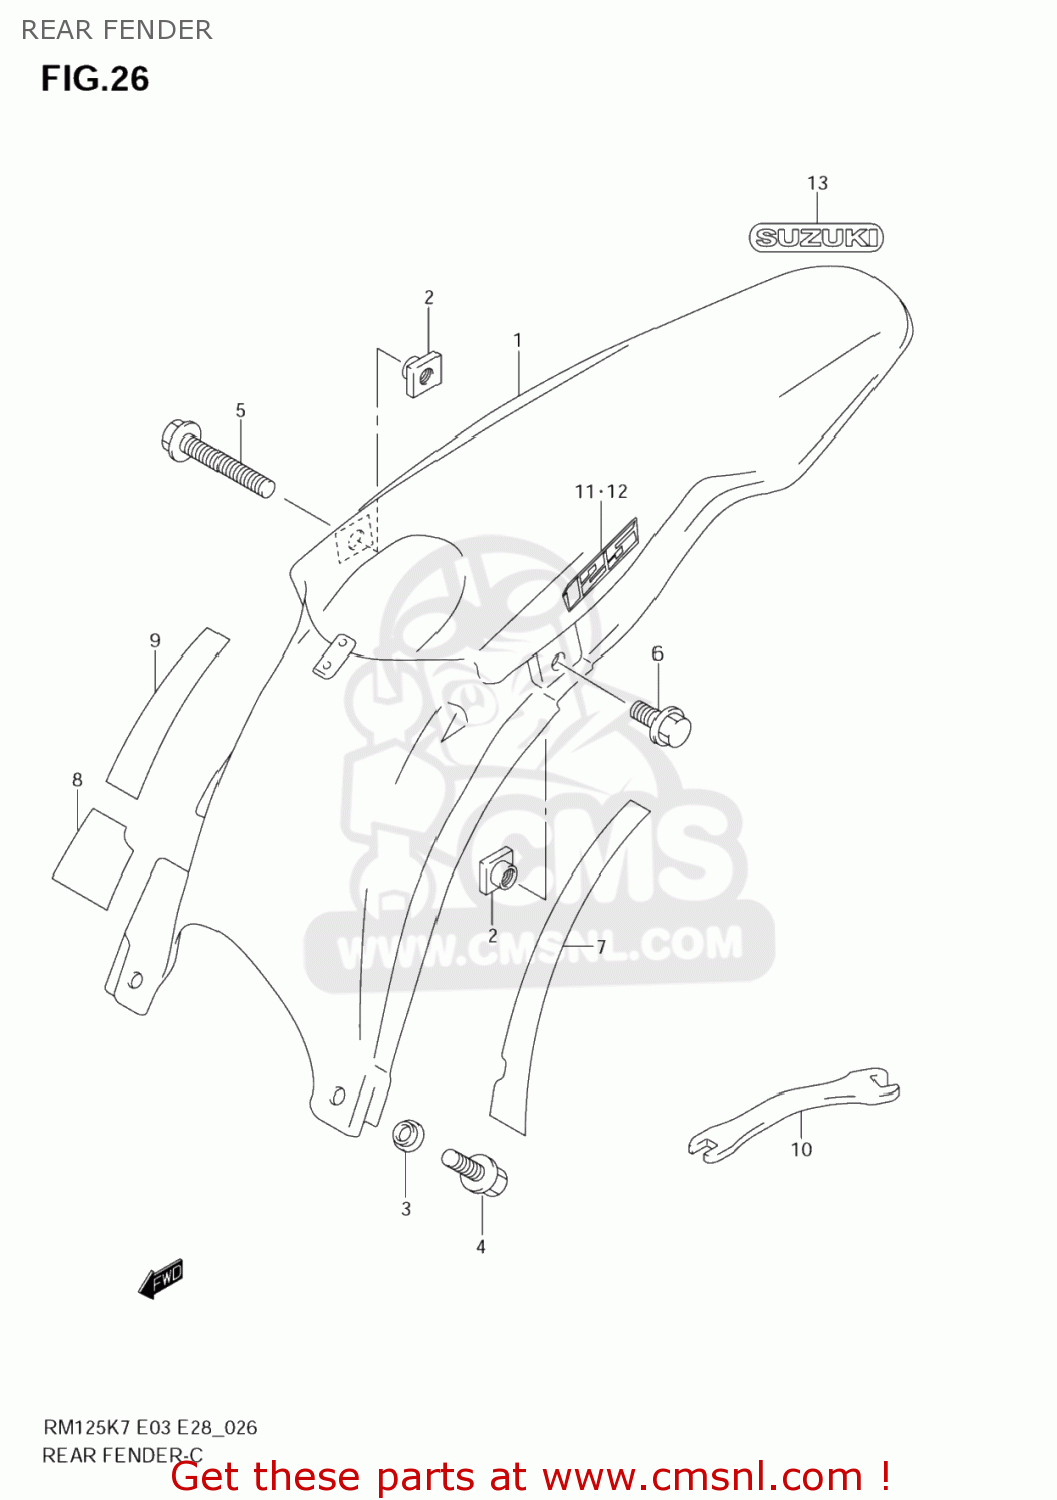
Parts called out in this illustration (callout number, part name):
1	FENDER,RR
2	NUT
3	WASHER
4	BOLT
5	BOLT
6	BOLT(6X16)
7	CUSHION,RR FENDER NO.1
8	CUSHION,RR FENDER NO.2
9	CUSHION,RR FENDER NO.3
10	OPEN SPANNER(6.4X6.8)
11	TAPE,RR FENDER,R
12	TAPE,RR FENDER,L
13	EMBLEM,RR
